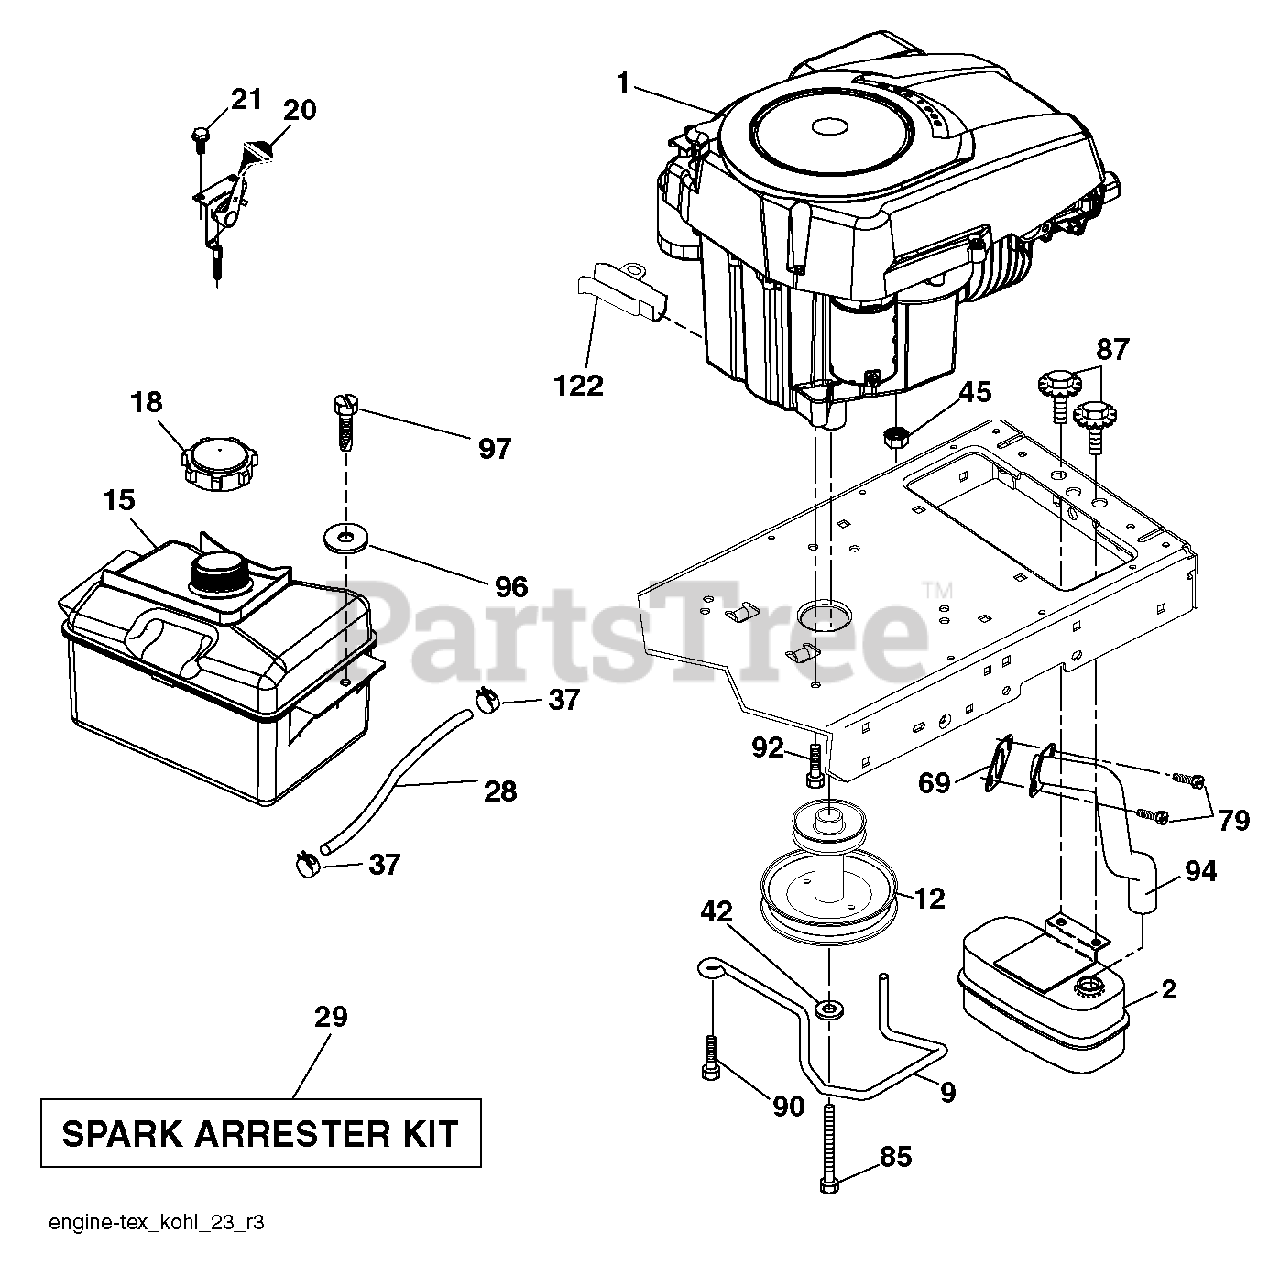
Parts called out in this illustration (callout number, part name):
2	MUFFLER.SINGLE.LRG.BRIGGS.KOHL
12	PULLEY ENGINE
15	FUEL.TANK.ASM.1.5.GAL.NON-EPA
18	CAP ASM.FUEL.2.25"FR.
21	SCREW.#10 X 0.750.BOS (2 2)
28	LINE.FUEL.20
29	KIT.SPARK ARRESTOR(392390 B&S)
37	HOSE CLAMP
42	LOCKWASHER
45	NUT
69	GASKET.EXHAUST.KOHLER
79	SCREW.SOCKET HD.5/16-1
85	BOLT HEX 7/16-20X4-1/4"
87	BOLT, 5/16-18 X 1 3/4
90	SCREW 3/8-16X1
92	SCREW 3/8-16X1
94	RP.TUBE.EXHAUST.KOHL.COURAGE
97	SCREW HEXWSHR 1/4-20X3/4
122	EXTENSION DRAIN OIL
